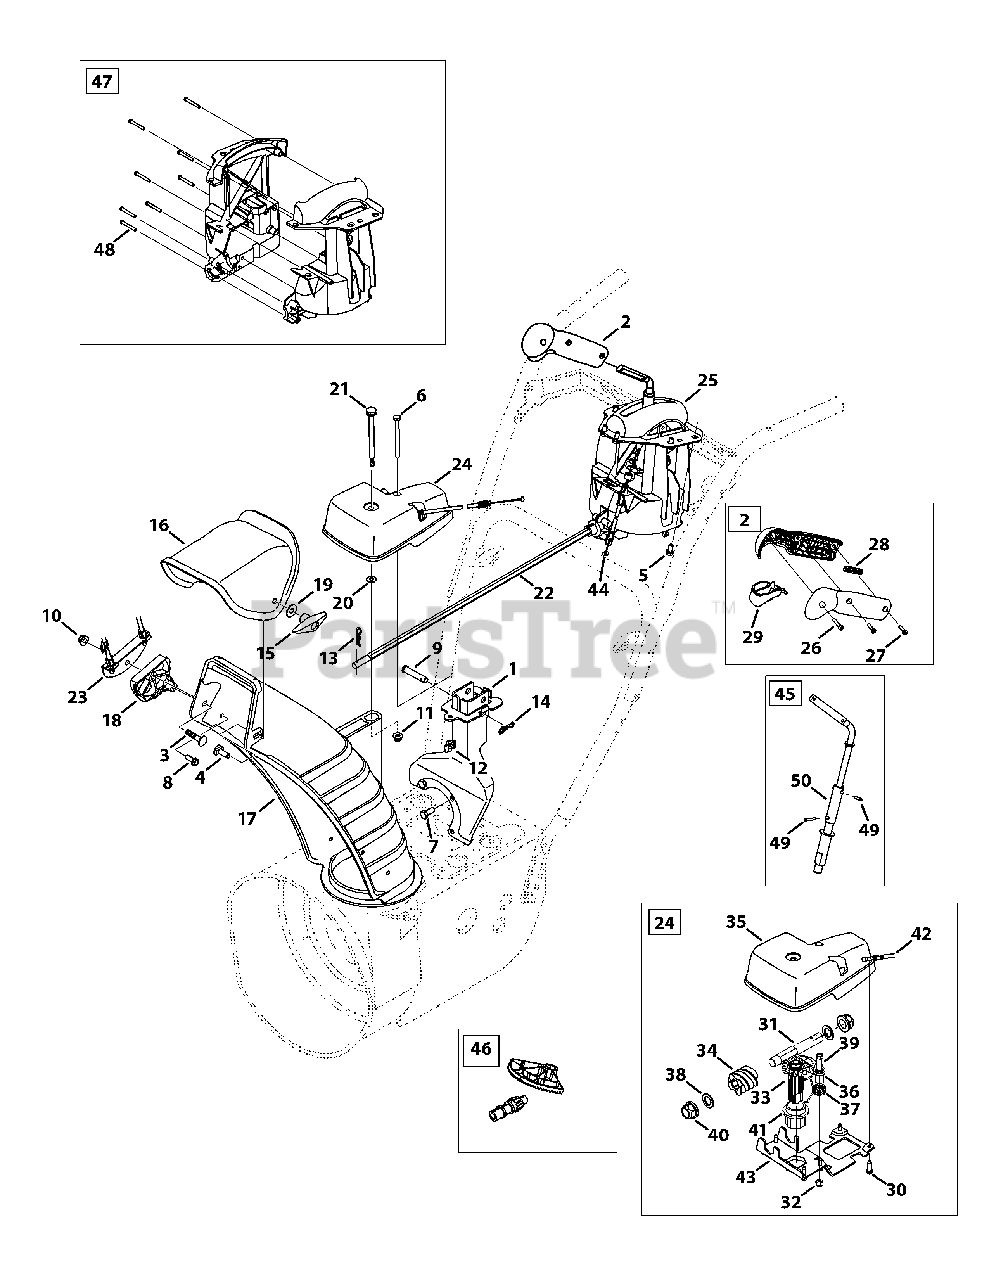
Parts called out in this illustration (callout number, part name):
1	Chute Support Bracket
2	Handle Assembly
3	Bolt, Carriage, 5/16-18 x 1.50
4	Bolt, Carrier, 5/16-18 x 1.00
5	Screw, HL, 1/4-15 x 0.50
6	Hex Head Screw, 1/4-20 x 3.00
7	Hex Head Screw, 5/16-24 x .750
8	Screw, HL, 1/4-15 x 0.750
9	Clevis Pin, 3/8 x 1.87
10	Nut, Flangelock, 5/16-18
11	Nut, Flangelock, 1/4-20
12	Wing Nut, 1/4-20
13	Internal Cotter Pin
14	Bow-Tie Cotter Pin
15	Wing Knob, 5/16-18
16	Chute, Upper
17	Chute, Lower
18	Cable Guide, Chute Tilt
19	Washer, Flat, .349 x .879
20	Washer, Flat, .25 x .630
21	Screw, Shoulder, .312 x 3.5 x 1/4-20
22	Chute Rod, 3/8 Hex
23	Cable Bracket
24	Gearbox Assembly, Chute Rotation
25	Chute Control, 4-Way
26	Screw, #8 x 1.00
27	Screw, 8-32 x .750
28	Joystick Plug
29	Joystick Trigger
30	Screw, 12-16 x .75
31	Hex Shaft
32	Hexlock Nut, 1/4-28
33	Gear, 14 T
34	Worm
35	Gear Cover
36	Pawl Lock
37	Torsion Spring, .721 ID x .474
38	Washer, Flat, .625 x 1.0 x .067
39	Screw, Shoulder, .340 x .950 x 1/4-28
40	Hex Bearing
41	Flange Bearing
42	Cable Lock
43	Gear Bracket
44	4-Way Cable
44	4-Way Cable w/Clip
45	Shift Assembly
46	Gear Set Assembly
47	Handle Housing Assembly
48	Screw, #8-18 x 1.250
49	Pin, Roll
50	Block, Asm Joint
